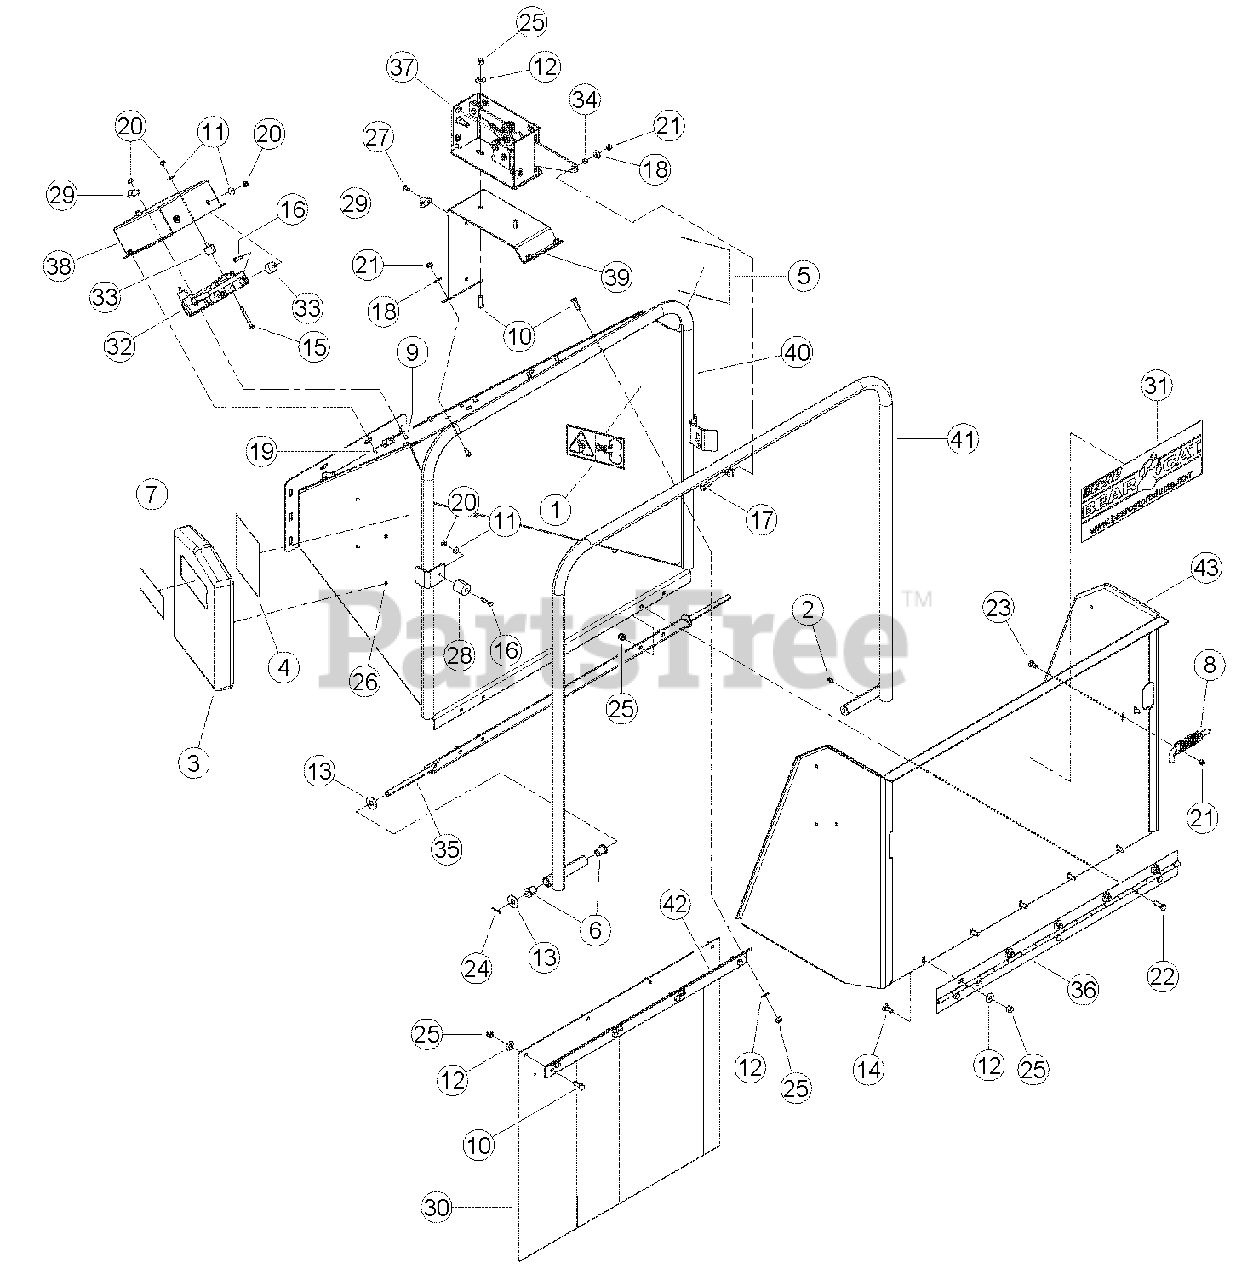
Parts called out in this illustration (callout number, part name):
1	DECAL, BLADE DANGER ISO
2	FITTING, 1/4 SELF-TAP GREASE
3	CONTAINER, INSTRUCTION MANUAL
4	DECAL, FEED POSITION
5	DECAL, FEED POSITION
6	BUSHING, 1/2 X 1 FLANGE LUBE
7	DECAL, MULTILINGUAL MANUAL
8	LATCH, RH HINGE
9	BOLT, 1/4 X 1 HEX HD GR5 ZP
10	BOLT, 3/8 X 1 HEX HD GR5 ZP
11	WASHER, 1/4 FLAT ZP
12	WASHER, 3/8 FLAT ZP
13	WASHER, 1/2 FLAT ZP
14	BOLT, 3/8 X 1 CRG GR5 ZP
15	BOLT, 1/4 X 2-1/4 HEX HD GR5 ZP
16	BOLT, 1/4 X 1-1/4 HEX HD GR5 ZP
17	BOLT, 5/16 X 1 HEX HD GR5 NC ZP
18	WASHER, 5/16 FLAT ZP
19	BOLT, 1/4 X 5/8 HEX HD GR5 ZP
20	NUT, 1/4 NE NYLOCK ZP
21	NUT, 5/16 NE NYLOCK ZP
22	BOLT, 3/8 X 1-1/4 HEX HD GR5 ZP
23	BOLT, 5/16 X 3/4 CRG GR5 NC ZP
24	PIN, 1/8 X 1 COTTER ZP
25	NUT, 3/8 NE NYLOCK ZP
26	RIVET, AL BLIND 1/4 X 1/2 DOME HEAD
27	RIVET, AL BLIND 1/4 X 3/4 DOME HEAD
28	BUMPER, RECESSED RUBBER
29	CLAMP, CABLE MOUNT
30	FLAP, CHUTE
31	DECAL, BEARCAT WEB
32	CONTROLLER, PLUS 1 CHIPPER
33	BUMPER, 1 OD. W/1/4 STUD
34	SPACER, IDLER PIVOT
35	WELDMENT, CONTROL PIVOT
36	HINGE, EXTENSION TRAY
37	ASSEMBLY, SWITCH BOX
38	ENCLOSURE, PLUS 1 MOUNT
39	MOUNT, SWITCH BOX
40	WELDMENT, CHIPPER CHUTE
41	WELDMENT, CONTROL ARM
42	SUPPORT, CHIPPER FLAP
43	WELDMENT, EXTENSION TRAY W/O TABS
